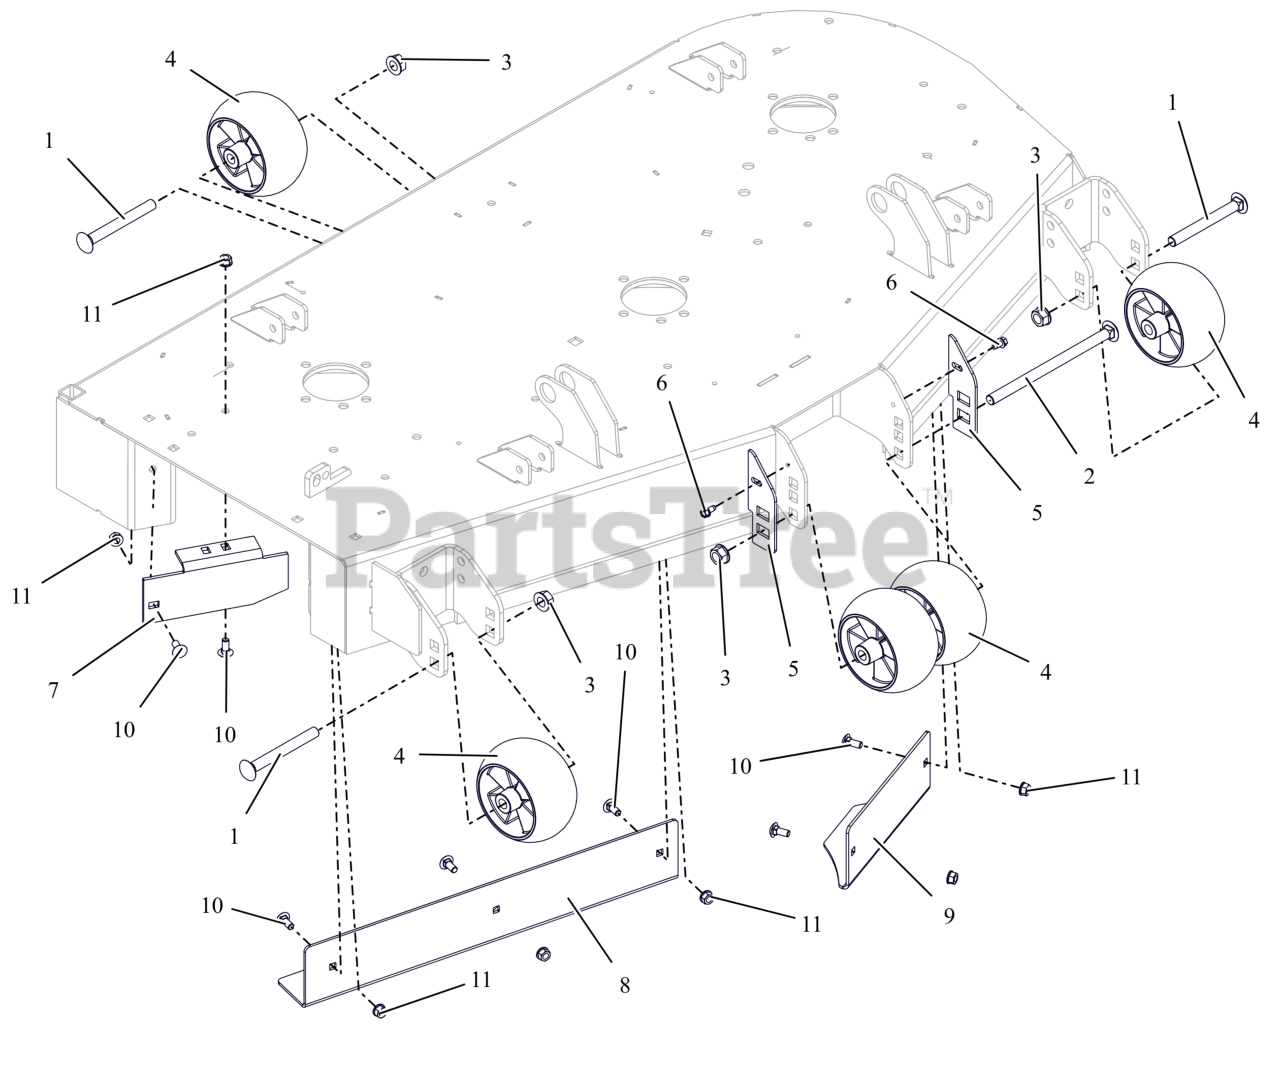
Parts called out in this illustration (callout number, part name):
1	BLT-RHNS .50-13X4.50 G5 ZCC NS
2	BLT-RHSN .50-13X8.00 G5 ZCC NS
3	NUT-LK-CTR-FLG .500-13 GG ZCC
4	WHEEL, ANTI SCALP - 5X3 CTR W/RIBS
5	PLATE, ANTI SCALP WHEEL 60" (ORANGE)
6	SCR-TAP .25-20X.50 HWH ZCC
7	BAFFLE, 44/48" SIDE DISCHARGE
8	BAFFLE, 48" RH VACUUM (ORANGE)
9	BAFFLE, 44/48" LH VACUUM (ORANGE)
10	BLT,RHSN .31-18X.75 G5 ZCC
11	NUT,LK-CTR-FLG .31-18 GF ZCC
